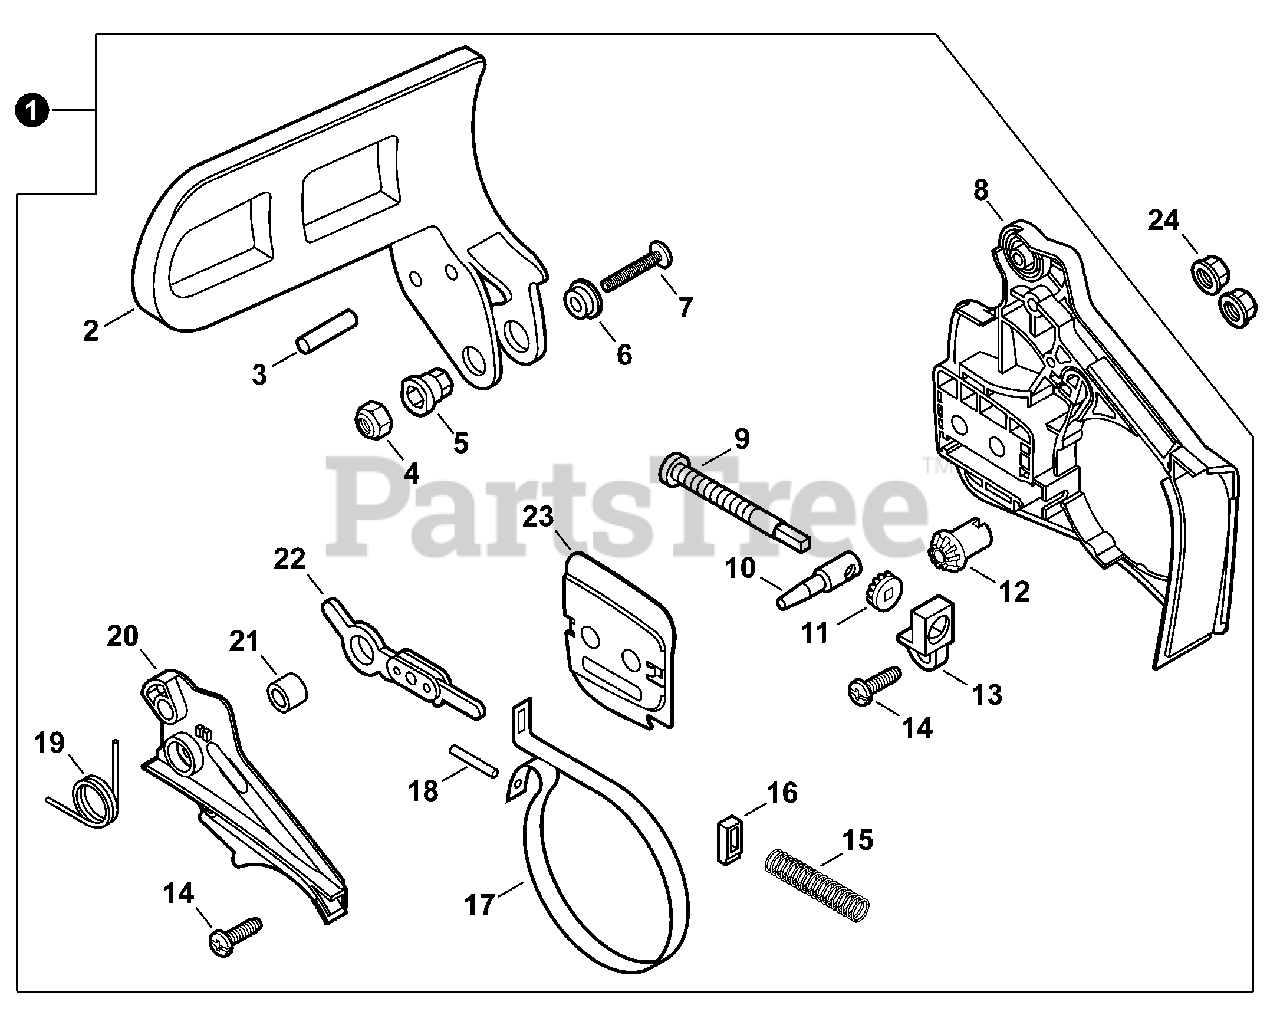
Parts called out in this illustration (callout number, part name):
1	BRAKE ASSY, CHAIN
2	LEVER, BRAKE
3	PIN 3×26
4	NUT, LOCK M5
5	COLLAR 5
6	COLLAR 5.3×10×13×L5
7	SCREW 5×32
8	GUARD, SPROCKET
10	TENSIONER, CHAIN
11	GEAR, BEVEL
12	GEAR, BEVEL
13	COLLAR 8
14	SCREW 4×12
15	SPRING, COMPRESSION
17	BAND, BRAKE
18	PIN, SPRING 3x-9.8
19	SPRING, TORSION
20	COVER, BRAKE
21	SPACER 8×12×9
22	CONNECTOR, BRAKE
23	PLATE, GUIDE - OUTER
24	NUT, FLANGE M6
